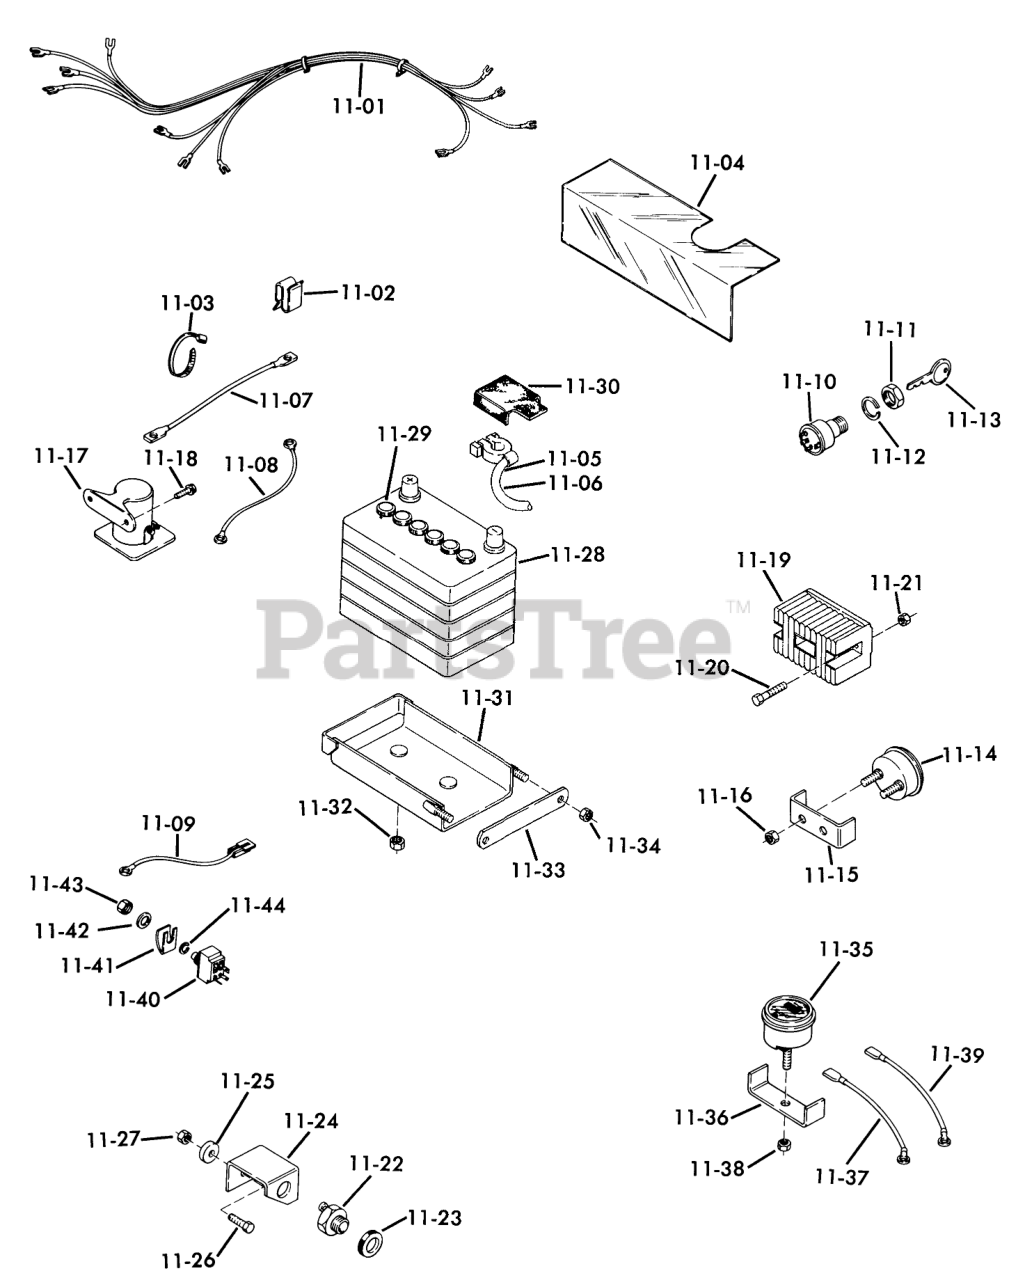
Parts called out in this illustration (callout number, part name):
11-01	WIRING HARNESS & DIA
11-02	SPEED CLIP
11-03	PLASTIC TIE
11-04	CONTROL PROTECTOR
11-05	Wire-Ground
11-06	WIRE SOLENOID
11-07	Wire
11-08	WIRE ASSY
11-09	Wire Assy.
11-10	SWITCH-IGNITION
11-12	LOCKWASHER
11-13	Key-EL
11-14	AMMETER W/CLAMP
11-15	Clamp
11-16	HEX NUT 10-32 E.S.
11-17	Solenoid
11-18	Screw
11-19	REGULATOR-RECTIFIER
11-20	Bolt
11-21	Nut
11-22	SWITCH SAFETY
11-23	NUT-SPECIAL 9/16-18
11-24	Bracket
11-25	WASHER
11-26	BOLT
11-27	Nut
11-28	BATTERY
11-30	Cover Battery Term
11-31	BATTERY BOX ASSY R (NS)
11-32	Nut
11-33	LINK BATTERY CLAMP
11-34	Nut
11-35	Hour Meter
11-36	Clamp
11-37	SY WIRE HR METER G
11-38	Nut
11-39	Wire Assy
11-40	SWITCH-CLUTCH
11-41	CLIP-SWITCH
11-42	WASHER
11-43	NUT-HEX
11-44	TAB-WASHER
